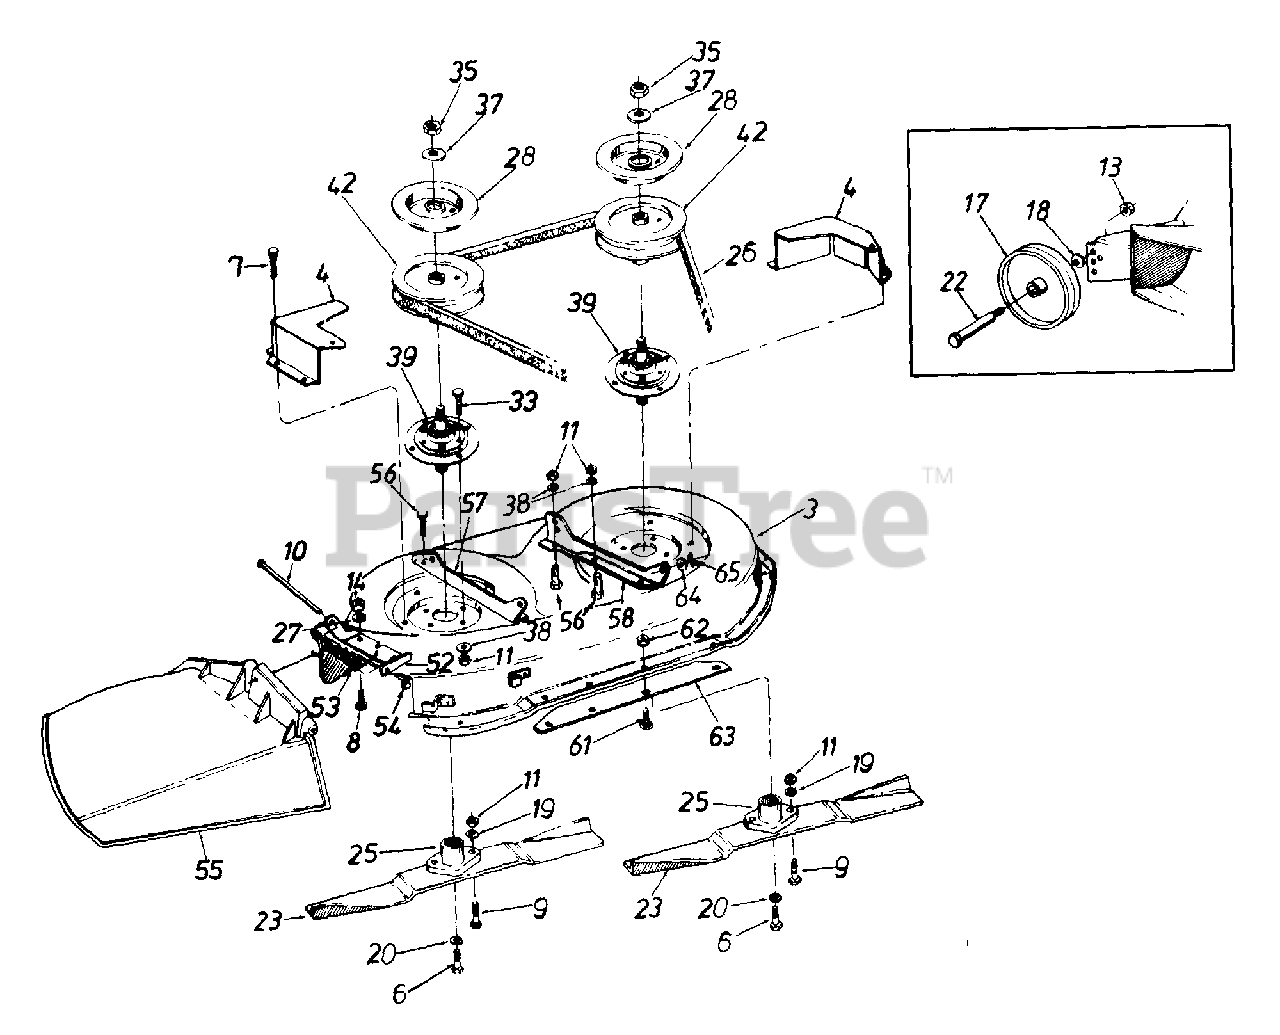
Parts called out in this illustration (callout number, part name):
3	38" Deck Ass'y. w/o Deck Wheels
6	Hex Bolt 3/8-24 x 1.0" Lg.
7	Hex Wash. Hd. TT-Tap Scr. 1/4-20 Thd. (38" Deck)
8	Hex Bolt 1/4-20 x .62" Lg. (38" Deck)
9	Hex Bolt Special 5/16-24 x 1.0"
10	Hinge Pin
11	Hex Nut 5/16-24 Thd.
13	Hex Top L-Nut 3/8-16 Thd.
14	Hex Nut 1/4-20 Thd.
17	Deck Wheel - 5"
18	Bell-Wash. .40" I.D. x .88" O.D.
19	L-Wash. 5/16" I.D.
20	L-Wash. 3/8" I.D. - H.D.
22	Shld. Bolt .498" Dia. x 1.53"
23	High-Lift Blade (38" Deck)
25	Blade Adapter
26	"V" - Belt (38" Deck)
27	Bell-Wash. 1/4" I.D.
28	Brake Disc
33	Hex Bolt 5/16-24 x .75" Lg. (38" Deck)
35	Hex Jam Nut 5/8-18 Thd.
37	L-Wash. 5/8" I.D.
38	Bell-Wash. .345" I.D. x .88" O.D.
39	Blade Spindle Ass'y. Comp.
42	5" Dia. Pulley
52	Hinge Mtg. Brkt.
53	Torsion Spring
54	Push Nut
55	Chute Ass'y. Comp.
56	Hex Bolt 5/16-24 x .75" Lg.
62	Hex Sems Nut 1/4-20 Thd. (38" Deck)
65	Hairpin Clip 3/8" Dia.
